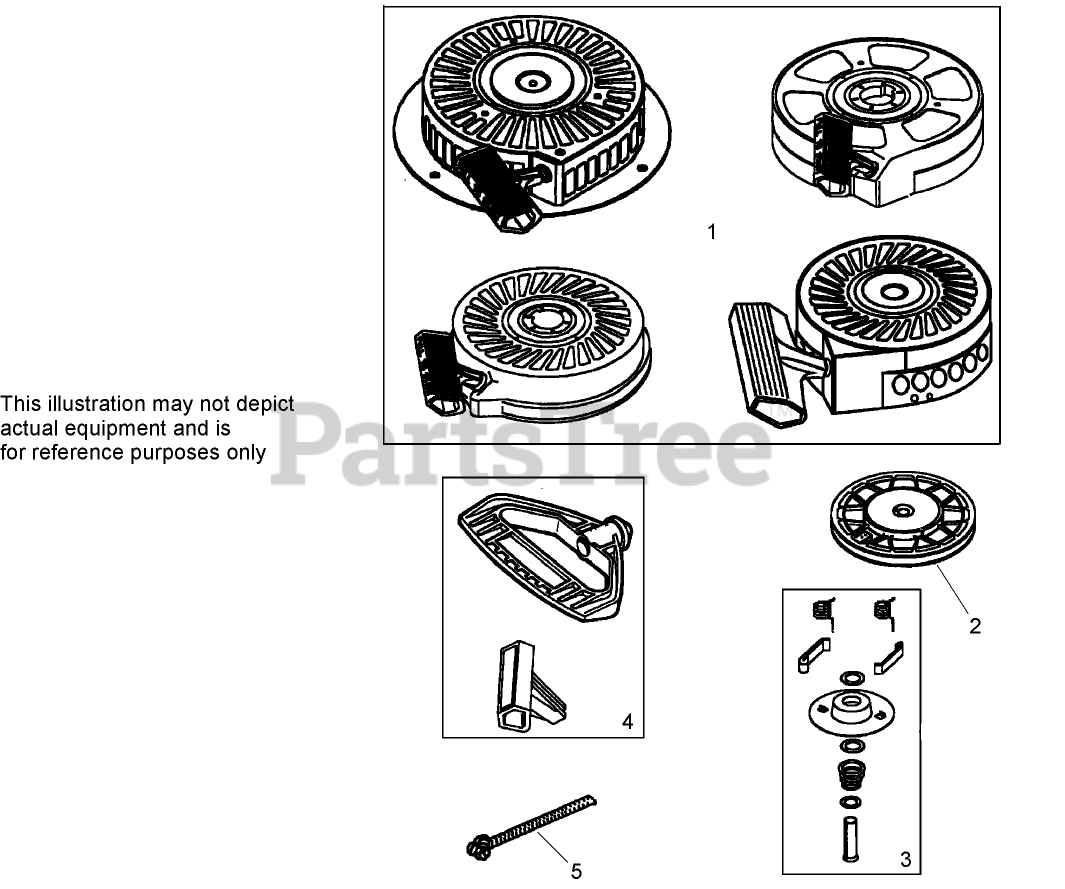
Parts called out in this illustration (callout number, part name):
1	Starter-Rewind
2	Pulley and Rewind Spring ASM
3	Repair Kit
4	Handle-Starter, Mitten Grip
5	Rope-Starter (98 cut to length)
